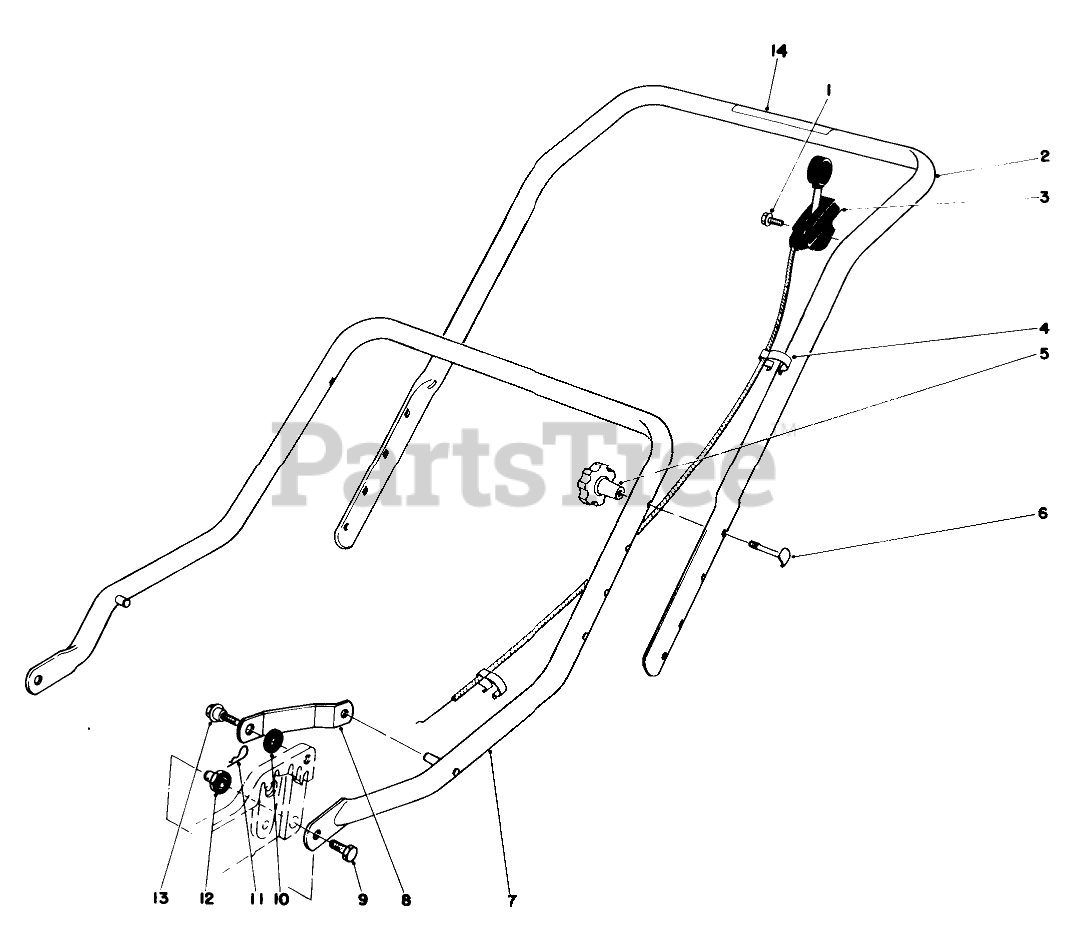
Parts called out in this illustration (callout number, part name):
2	Upper Handle
3	Throttle Control
4	BOWDEN CLIP
6	HANDLE SCREW
7	Lower Handle
8	HANDLE LATCH
9	SCREW-HH
10	SPACER
11	PIN-COTTER, HAIR
12	HANDLE PIVOT NUT
13	SCREW-SHOULDER
14	Decal
